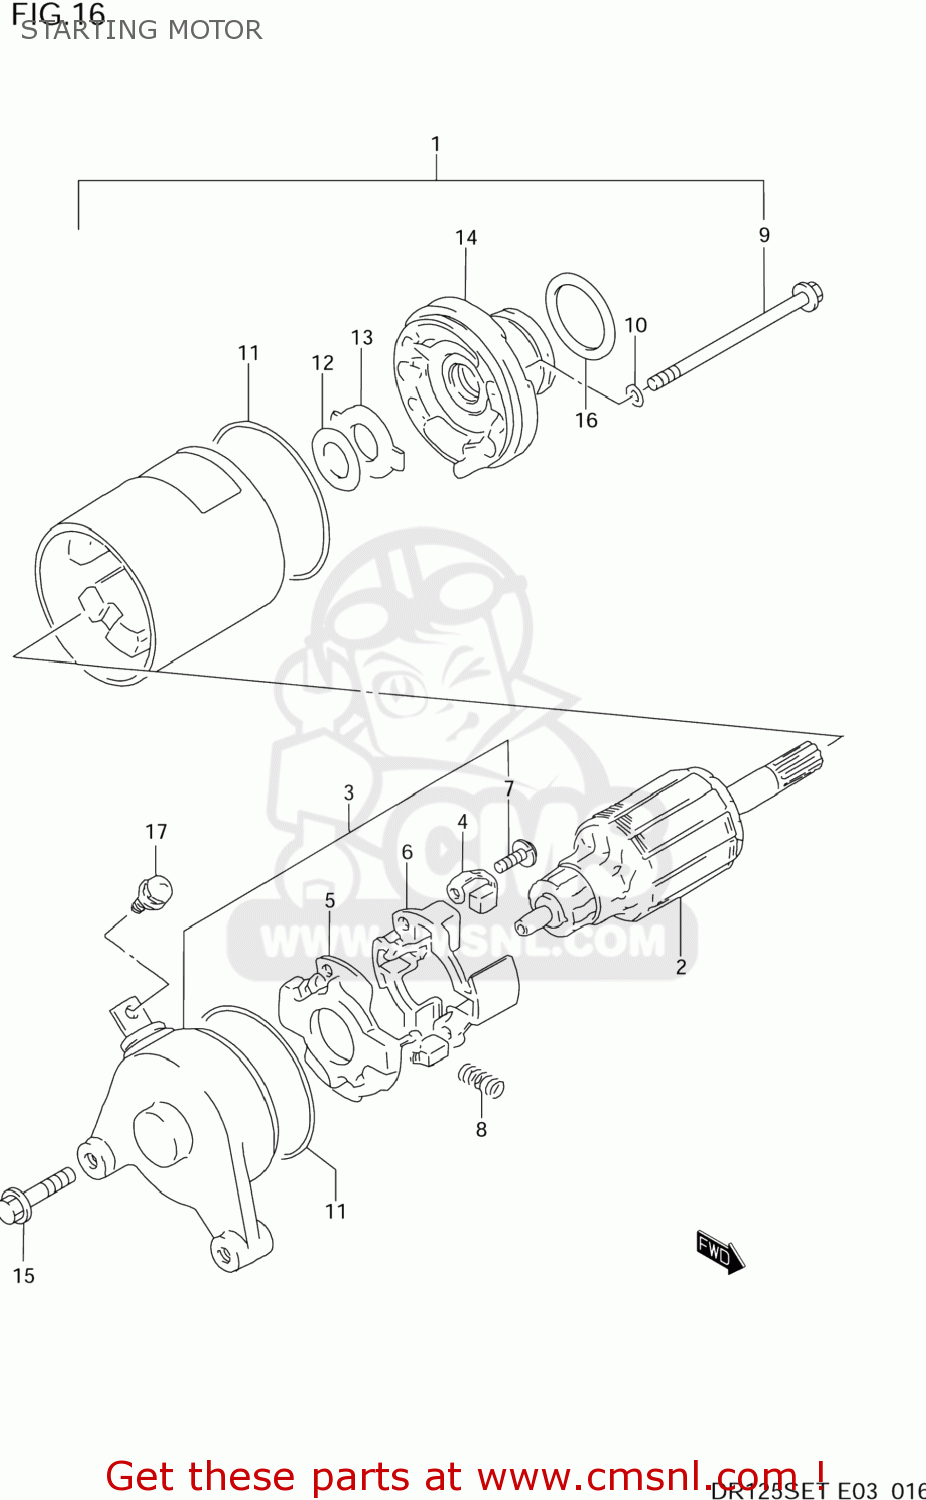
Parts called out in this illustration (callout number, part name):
1	MOTOR ASSY,STARTING
2	ARMATURE
3	FRAME ASSEMBLY,COMMUTATOR
4	BRUSH
5	BRUSH SUB ASSEMBLY
6	HOLDER,BRUSH
7	SCREW
8	SPRING
9	BOLT
10	O RING
11	O RING
12	SHIM
13	PLATE,LOCK
14	BRACKET
15	BOLT
16	O RING(D:3,ID:24.5)
17	SCREW(5X8)
